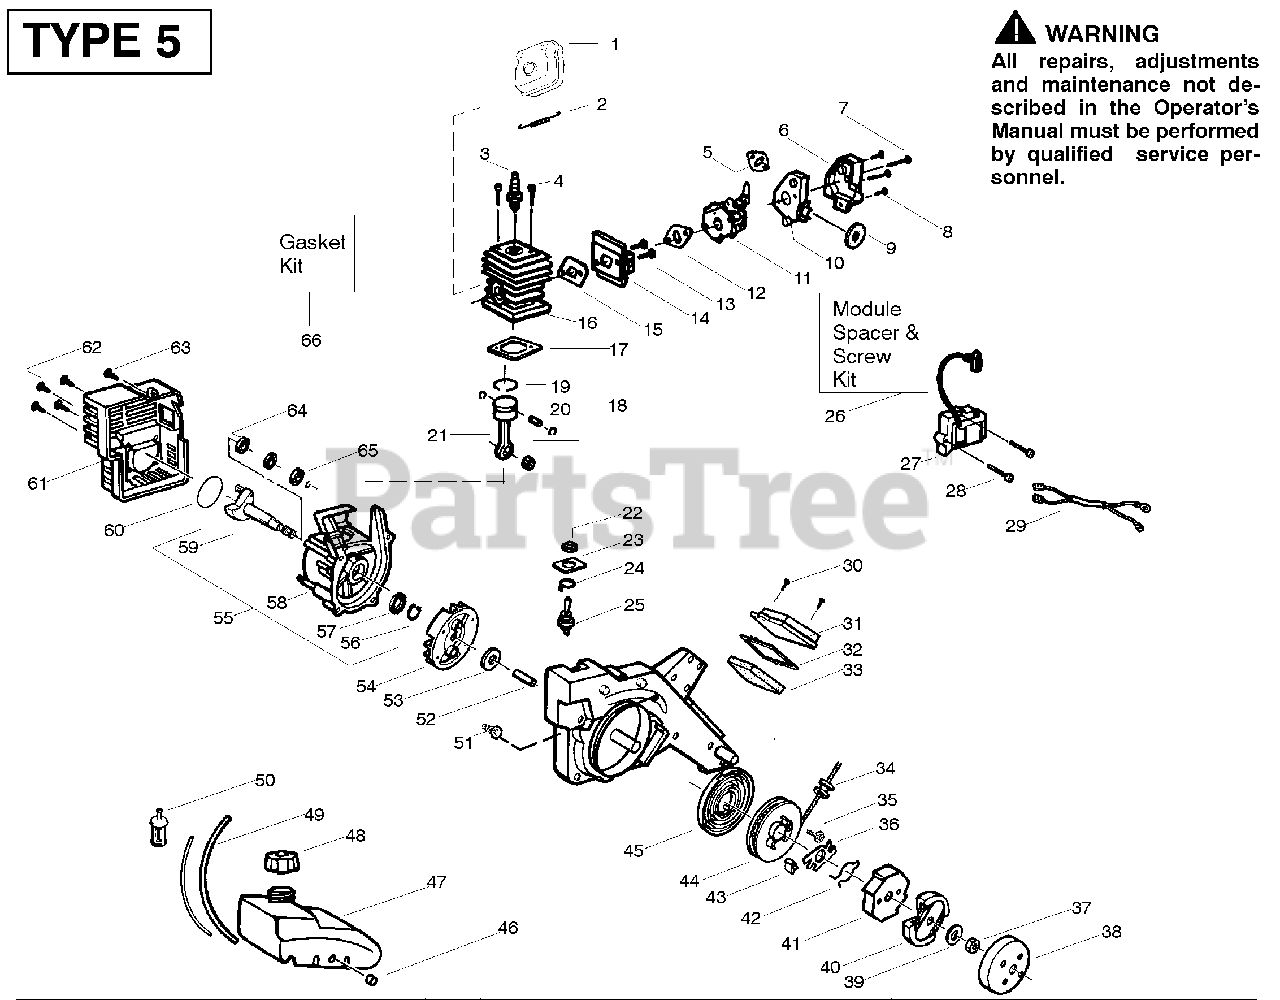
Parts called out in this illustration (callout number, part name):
1	Kit-Muffler
2	Spring-Muffler
3	Plug-Spark (RCJ-6Y)
5	Gasket-Carb/Bracket(kit)
6	Cover-Air Box
9	Seal-Foam (kit)
10	Base-Air Box
11	Kit-Carb. (Wt-630)
12	Gasket-Carb.(kit)
14	Adapter-Carb.
15	Gasket-Cyl./Carb. (kit)
16	Cylinder
17	Gasket-Cyl. (kit)
18	Kit-Piston
19	Ring-Piston
20	Retainer-Pin
21	Kit-Conn. Rod Assy.
22	Boot-Switch w/nut
23	Plate-Switch Indicator
24	Terminal-Grounding
25	Assy-Gound Switch
26	Kit-Mod. spacer/screw
27	Module-Ignition
29	Assy-Switch Wire
31	Cover-Air Filter
32	Gasket-Cover (kit)
33	Foam-Air Filter
36	Cam-Starter
38	Drum-Clutch
39	Washer-Flywheel
40	Assy-Clutch
41	Cup-Starter
42	Wire-Starter Dog
43	Dog-Starter
44	Kit-Starter Pulley
45	Spring-Starter
46	Isolator-Crankcase
47	Assy-Fuel Tank
48	Assy-Fuel Cap
49	Kit-Fuel Line
50	Assy-Fuel Pick-up
51	Clip-Pine Tree
52	Spacer-Flywheel
53	Washer-Flat
54	Assy-Flywheel
55	Assy-C/shaft & C/case
56	Retainer-C'shaft
58	Assy-C'case
59	Assy-Crankshaft
60	O-ring-c'case/shrd (kit)
64	Bearing-Inner
65	Bearing-Outer
66	Kit Gasket
